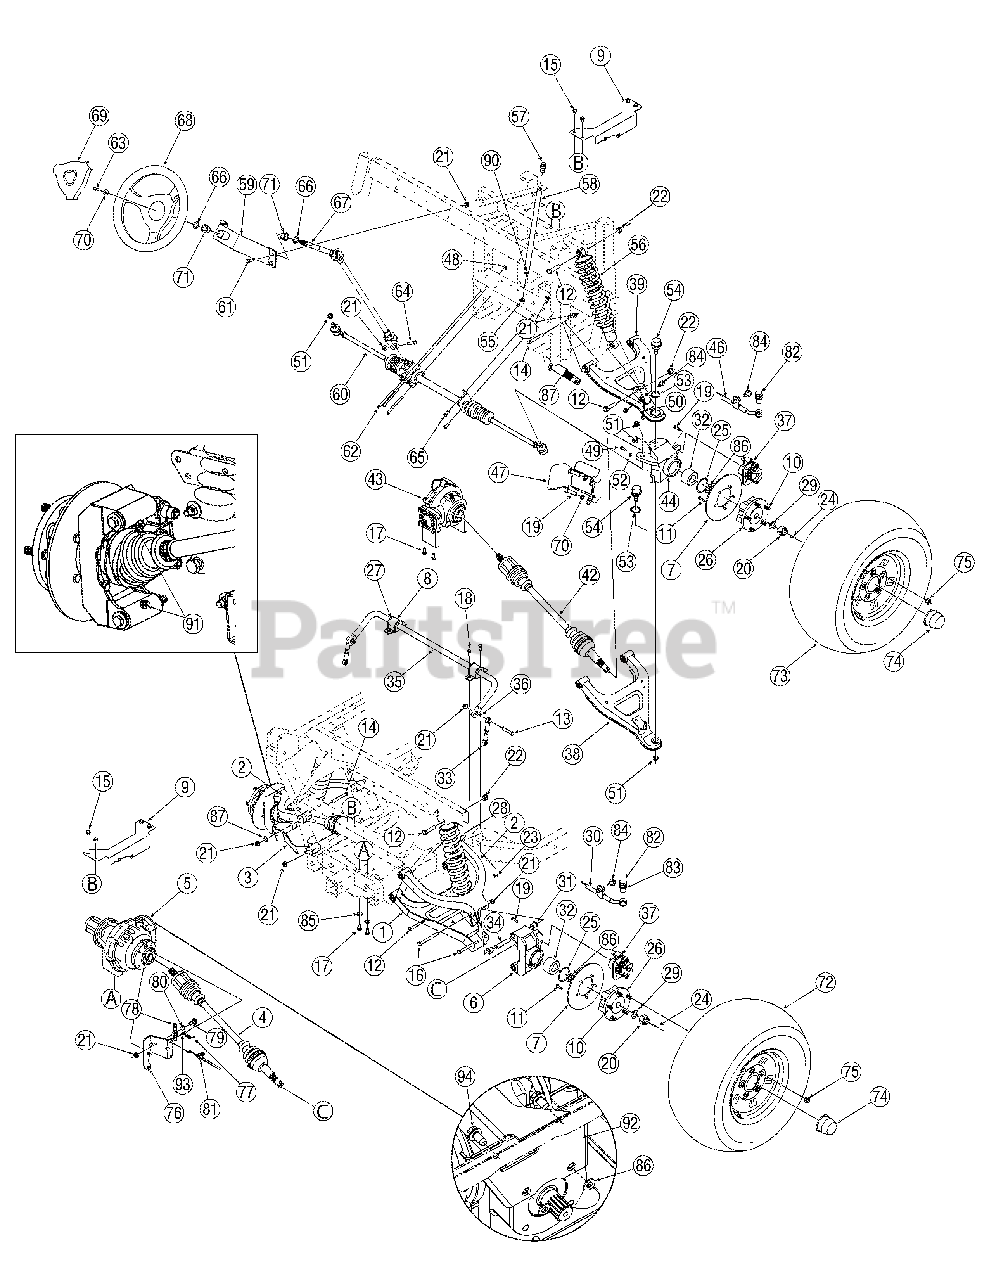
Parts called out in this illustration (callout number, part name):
1	Cont Assembly, lwr, r/rr
2	Cont Assembly, rr Upr
3	Cont Assembly, lwr, l/rr
4	Axle Assembly, cv Joint
5	Diff Assembly, Uv, complete
6	Hsg, rr, mach
7	Disc, brake, 8.00x.188
10	Stud, rib Neck, 7/16-14 X 1.6
11	Screw, 1/4-20, .625, gr5, lock
12	Screw, 1/2-13, 2.00, gr5, std
13	Screw, 3/8-18, 1.75, gr5
14	Screw, 3/8-16, 3.00, gr8, std
15	Scr, tt, 5/16-18, 0.500, hxindwsh
16	Screw, 3/8-16, 4.00, gr5
17	Screw, 3/8-16, .75, gr5, std
18	Screw, 5/16-24, .75, gr5, std
19	Screw, m8-1.25, 25.00
20	Nut, slotted, 22x1.5
21	Nut, flglk, 3/8-16, grf, nylon
22	Nut, hexlk, 1/2-13, grb, nylon
23	Nut, flglk, 5/16-18, grf, nylon
24	Pin, cot, 5/32, 1.25
25	Ring, ret, dho-60
26	Hub, Wheel
27	Bush, sway Bar
28	Shabs, 5.0 Stroke, rr
29	Wash, flat, .88 X 1.38 X .125, ht
30	Hose, brake, rear, right
31	Brg, flg, .625 X .750 X .750 Lg
32	Brg, dble Row, 60x30x37
33	Rod, cont, .375x3.886
34	Tube, pivot, rr/cont Arm
35	Bar, sway, rr
36	Washer, Flat, .407 x .812 x .135
37	Brake, hyd, caliper, frt
38	Cont Assembly,r/frt,lwr
39	Arm Assembly,r/frt,upr
42	Axle Assembly,cv Joint,4x4
43	Diff Assembly,cfd,4x4
44	Hsg,knuckle,r/frt,mach
46	Hose, brake, front, right
48	Nut, Flg Lk, 5/16-18
49	Screw,1/4-20,1.00,gr5,spec
50	Wire, Brake Line
51	Nut,nylock,m12x1.25
52	Nut,hex,1/4-20,gr5
53	Ring,ret,34x1.6
54	Ball Joint, bj14d-6201
55	Clamp,hose,.490 Dia.
56	Shabs,5.0 Stroke,frt
57	Vent,3/8 Dia
58	Hose,fuel Line
60	Steering Assembly
61	Screw,3/8-16,1.00,gr5,std
62	Screw,5/16-18,3.50,gr5,std
63	Screw,5/16-18,.75,gr5,patch
64	Screw,3/8-16,1.25,gr5,std
65	Screw,5/16-18,.75,gr5,std
66	Ring,e Type,.750
68	Wheel,strg,soft Grip 3 Spoke 5/8
68	Wheel,strg,Spoke,Cub Blue
69	Cvr,Wheel,steering Soft Grip
69	Cvr,Wheel,Steering,W/logo
70	Wash,bell,.340 X .872 X .060
71	Brg,flg,.754id X 1.00odx.925
72	Wheel Ass’y, r/compl,25x11-12
72	Tire Only, 25x11-12, AT
73	Wheel Ass’y, r/compl,25x10-12
73	Wheel Ass’y, compl,24x9.50-12, Turf
73	Tire Only, 25x10-12, AT
74	Cap, Wheel UV
75	Nut, lug, 7/16-14
77	Spr, ext, .38od x 2.10
78	Lvr, Ass’y, Diff Lock
79	Scr, shldr, .500 dia x .434
80	Brg, flg, nyliner, .500id x .34lg
81	Cbl, cont, diff, lock
82	Ftg, banjo ftg bolt, M10x1.00
83	Ftg, banjo ftg crush wash,10mm
84	Screw, tt, 1/4-20x.500
85	Washer, Flat, .385 x .870 x .092
86	Wash, Flat, .344 x .688 x .065
87	Axle, Frt, 4x2
90	Clamp, Hose, Adj.
94	Scr., tt, 3/8-16 x .750
